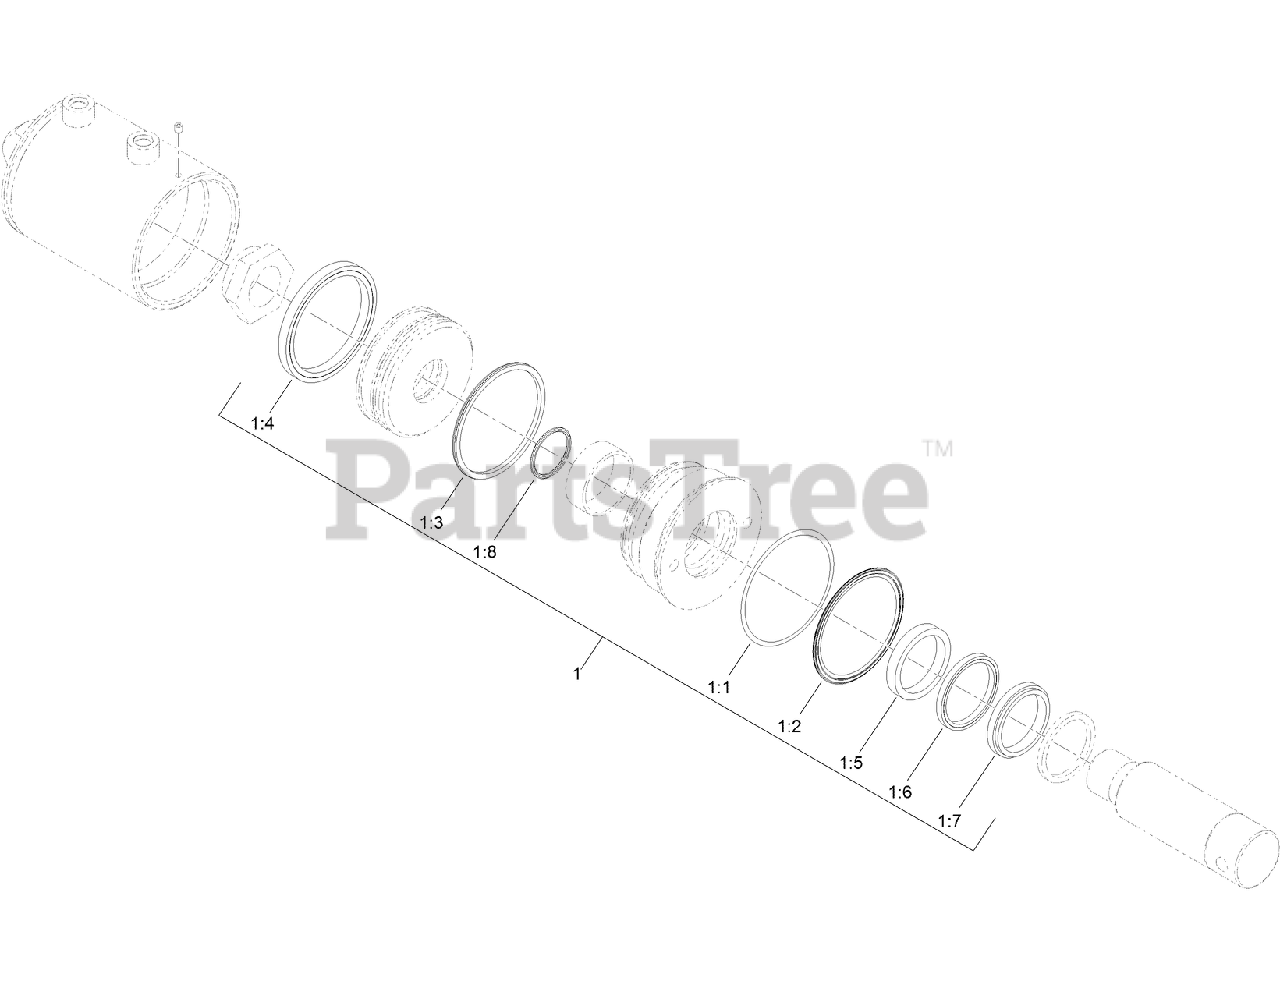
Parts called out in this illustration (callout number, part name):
1	SEAL KIT
1:1	Deck ASM
1:2	Deck ASM
1:3	SEAL-B P
1:4	Deck ASM
1:5	SEAL-P P S
1:6	BEARING-MODULAR
1:7	SEAL-DUST, HIGH TEMP
1:8	Deck ASM
